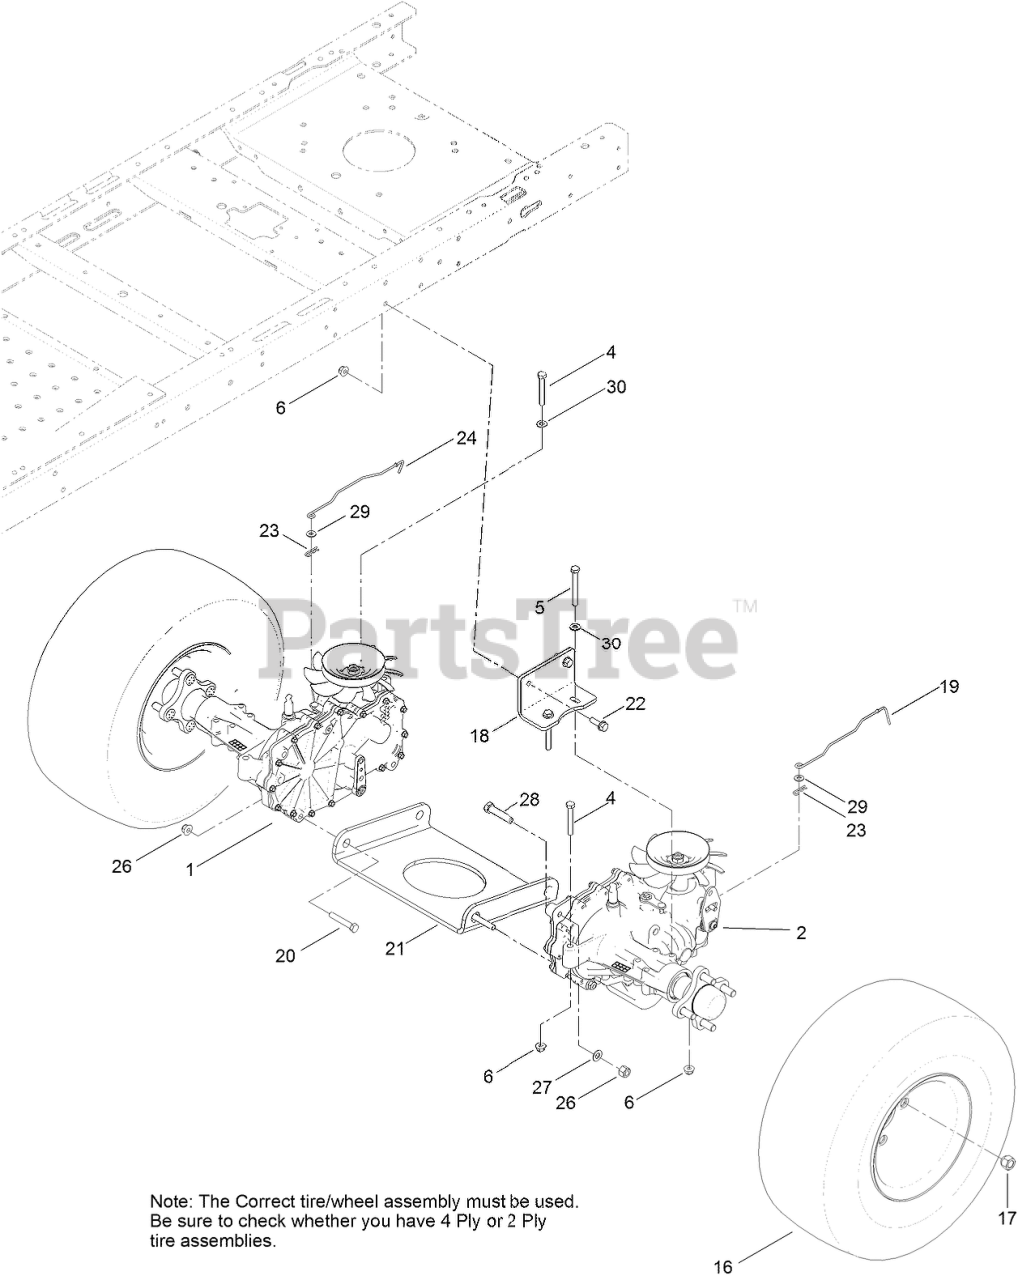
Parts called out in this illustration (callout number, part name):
1	RH HYDRO TRANSAXLE ASM
2	LH HYDRO TRANSAXLE ASM
4	SCREW-HH
5	SCREW-HH
6	NUT-HF, NI
16	4 PLY WHEEL AND TIRE ASM
16	2 PLY TIRE AND WHEEL ASM
17	NUT-LUG
18	MOUNT-HYDRO
19	ROD-BYPASS, LH
20	SCREW-HH
21	PLATE-CROSS, HYDRO
22	SCREW-HHF
23	PIN-COTTER
24	ROD-BYPASS, RH
26	NUT-LOCK, NI
27	WASHER-FLAT
28	SCREW-HH
29	WASHER
30	WASHER-PLAIN
